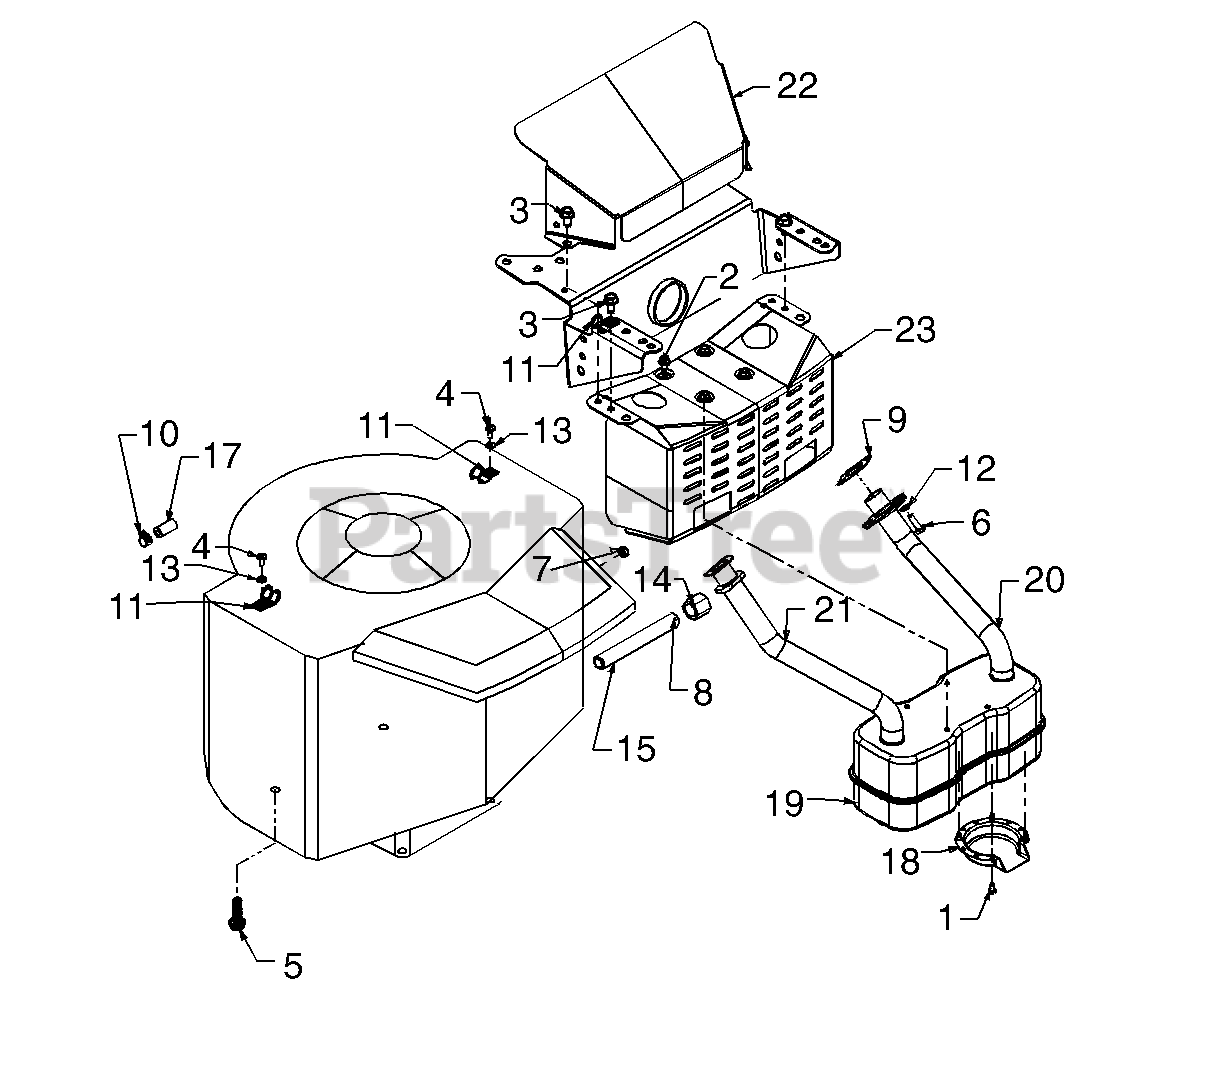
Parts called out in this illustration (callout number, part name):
1	Hex Tap Scr. #8-32 x .38" Lg.
2	Hex Wash. TT-Tap Scr. 1/4-20 x 5"
3	Hex Wash. TT-Tap Scr. 5/16-18 x .62" Lg.
4	Truss Mach. Scr. #10 x .5" Lg.
5	Hex Hd. Tap Scr. 3/8-16 x 1.25" Lg.
6	Hex Bolt 1/4-20 x .75" Lg.
7	Hex Sems Nut 1/4-20 Thd.
9	Exhaust Gasket
10	Hose Clamp
11	Clamp
12	L-Wash. 1/4" I.D.
13	Fl-Wash. .188" I.D. x .438" O.D.
14	Oil Drain Cap
15	Pipe Nipple 3/8 x 18 NPT.
17	Fuel Line 26" Lg.
18	Deflector: Muffler
19	Muffler
20	Exhaust Pipe-L.H.
21	Exhaust Pipe-R.H.
